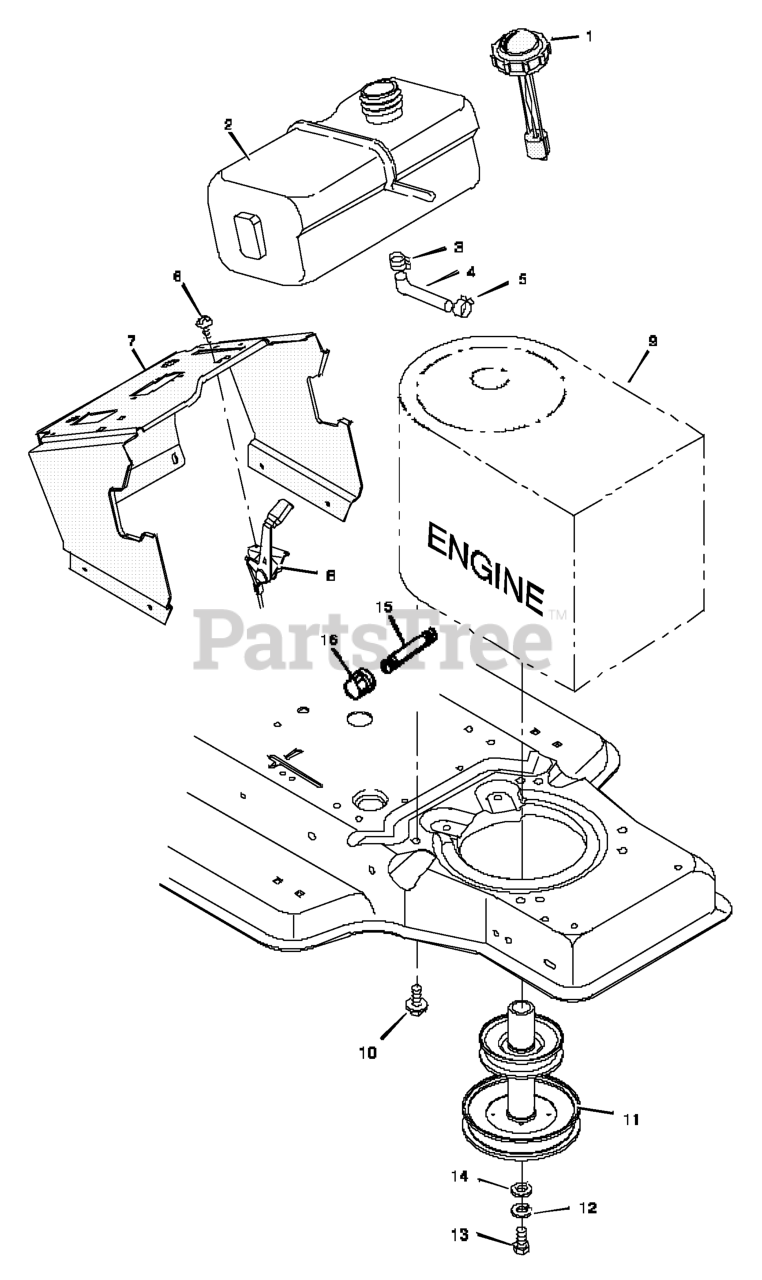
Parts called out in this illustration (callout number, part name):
1	Fuel Cap
2	Fuel Tank
3	Hose Clamp
4	Fuel Line
5	Hose Clamp
7	Support, Dash
8	Throttle Control
9	Engine *
10	Bolt, Engine Mount
11	Stack Pulley Assembly
12	Lockwasher
13	Bolt, Hex
15	Pipe, Oil Drain
16	Cap, Oil Drain
